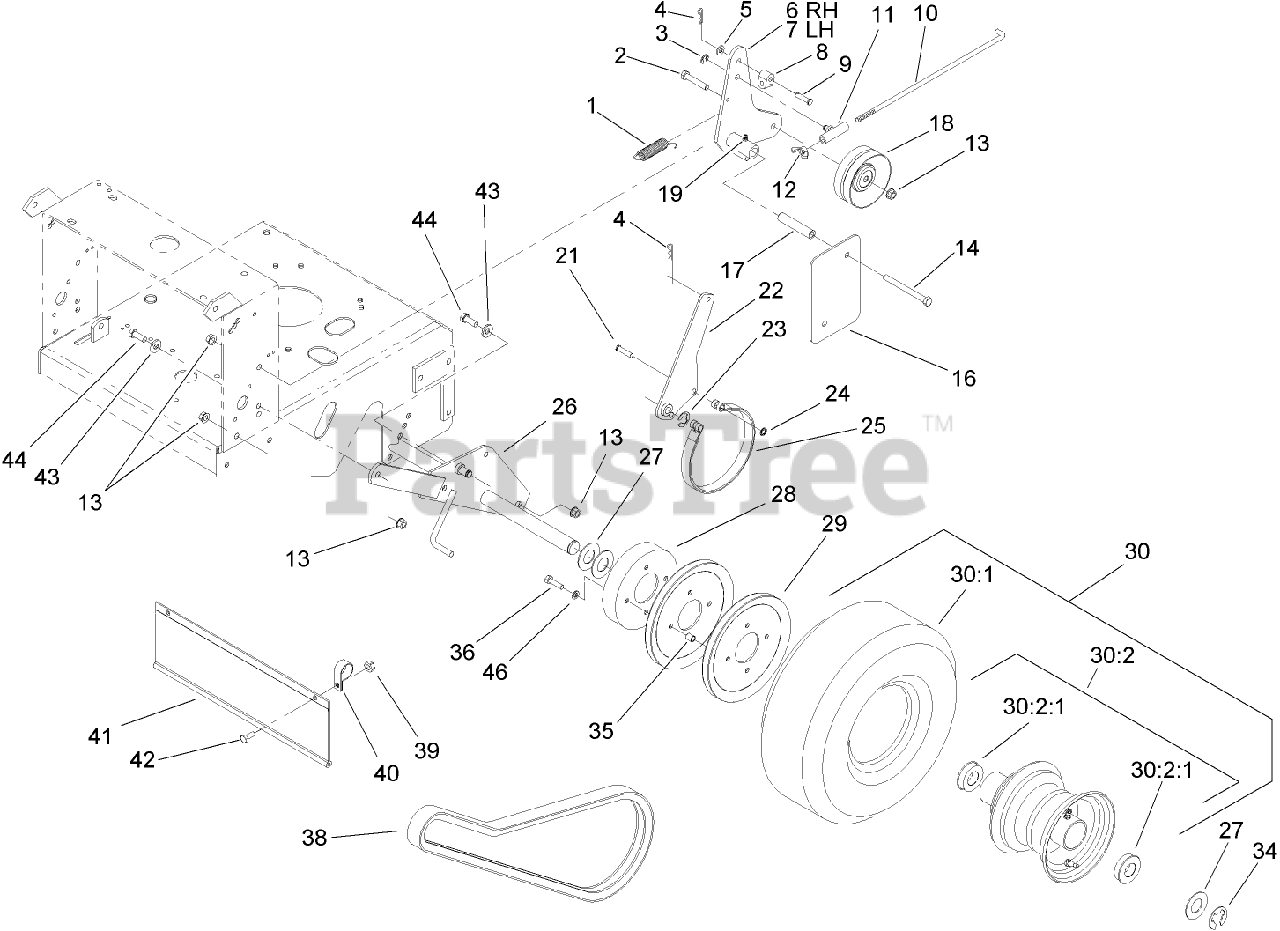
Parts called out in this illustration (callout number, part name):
1	SPRING-EXTENSION
2	SCREW-HH
3	RING-RETAINING
4	PIN-COTTER
5	WASHER-PLAIN
6	RH IDLER ARM ASM
7	LH IDLER ARM ASM
8	FITTING-ROD
9	PIN-CLEVIS
10	ROD-BRAKE
11	SWIVEL-BRAKE
12	WINGNUT-NYLOCK
13	NUT-HHF, WHIZ
14	SCREW-HH
16	SHIELD-WHEEL, DRIVE
17	SPACER-SHIELD
18	IDLER-DRIVE, WHEEL
19	FITTING-GREASE
21	PIN-CLEVIS
22	ARM-BRAKE
23	RING-RETAINING, EXTERNAL
24	NUT-PUSH
25	BAND-BRAKE
27	WASHER-SPACER
28	DRUM-BRAKE
29	SHEAVE-WHEEL, DRIVE
30	Wheel and Tire ASM
30:1	Tire-Turfmaster
30:2	WHEEL AND HUB ASM
30:2:1	BEARING-FLANGED
34	RING-SNAP
35	SPACER-SHEAVE, WHEEL
36	SCREW-HH
38	V-BELT
39	NUT-LOCK, NI
40	CLAMP-R
41	SHIELD-TRAILING
42	SCREW-HH
43	WASHER-BELLEVILLE
44	SCREW-HH
46	WASHER-LOCK
